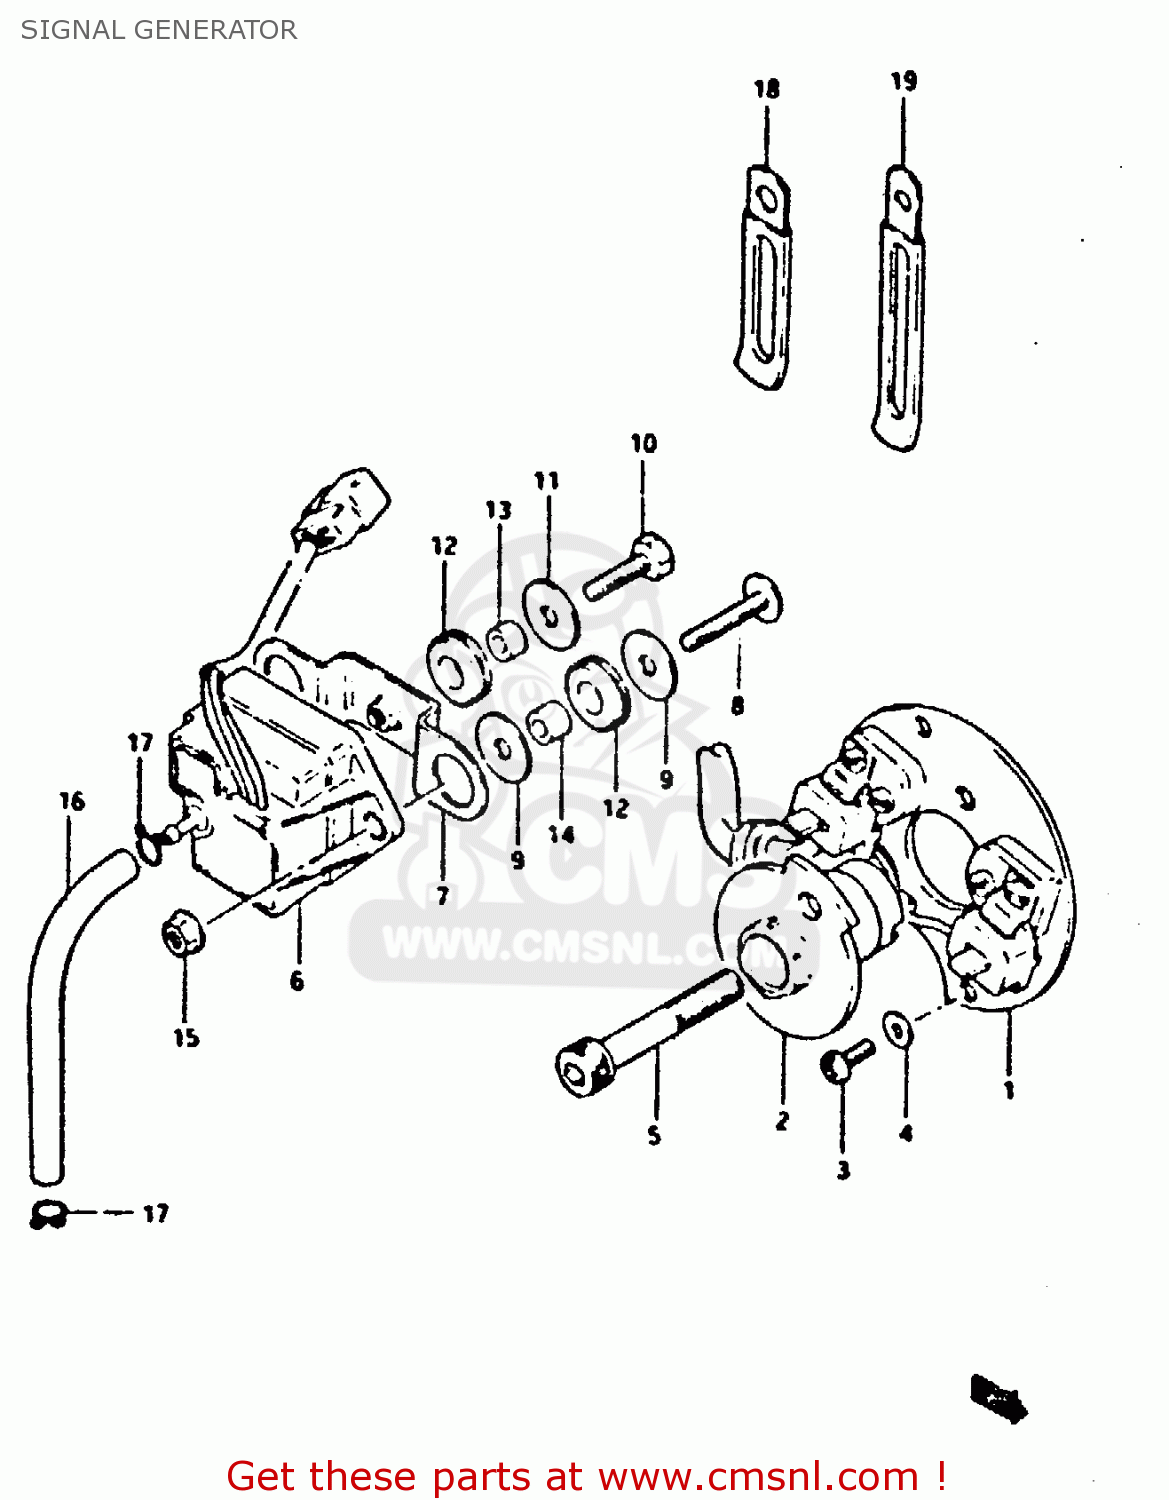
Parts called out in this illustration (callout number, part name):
1	GENERATOR ASSEMBLY,SIGNAL
2	GOVERNOR ASSEMBLY
3	SCREW(5X12)
4	WASHER(5.5X10X0.8)
5	BOLT
6	SENSOR ASSEMBLY,IGNITER
7	BRACKET,BOOST SENSOR
8	SCREW
9	WASHER
10	BOLT, UPPER
11	WASHER
12	CUSHION
13	SPACER(6.1X9X7.5)
14	SPACER (6.1X9X9)
15	NUT
16	HOSE
17	CLIP
18	CLAMP L:35
19	CLAMP
